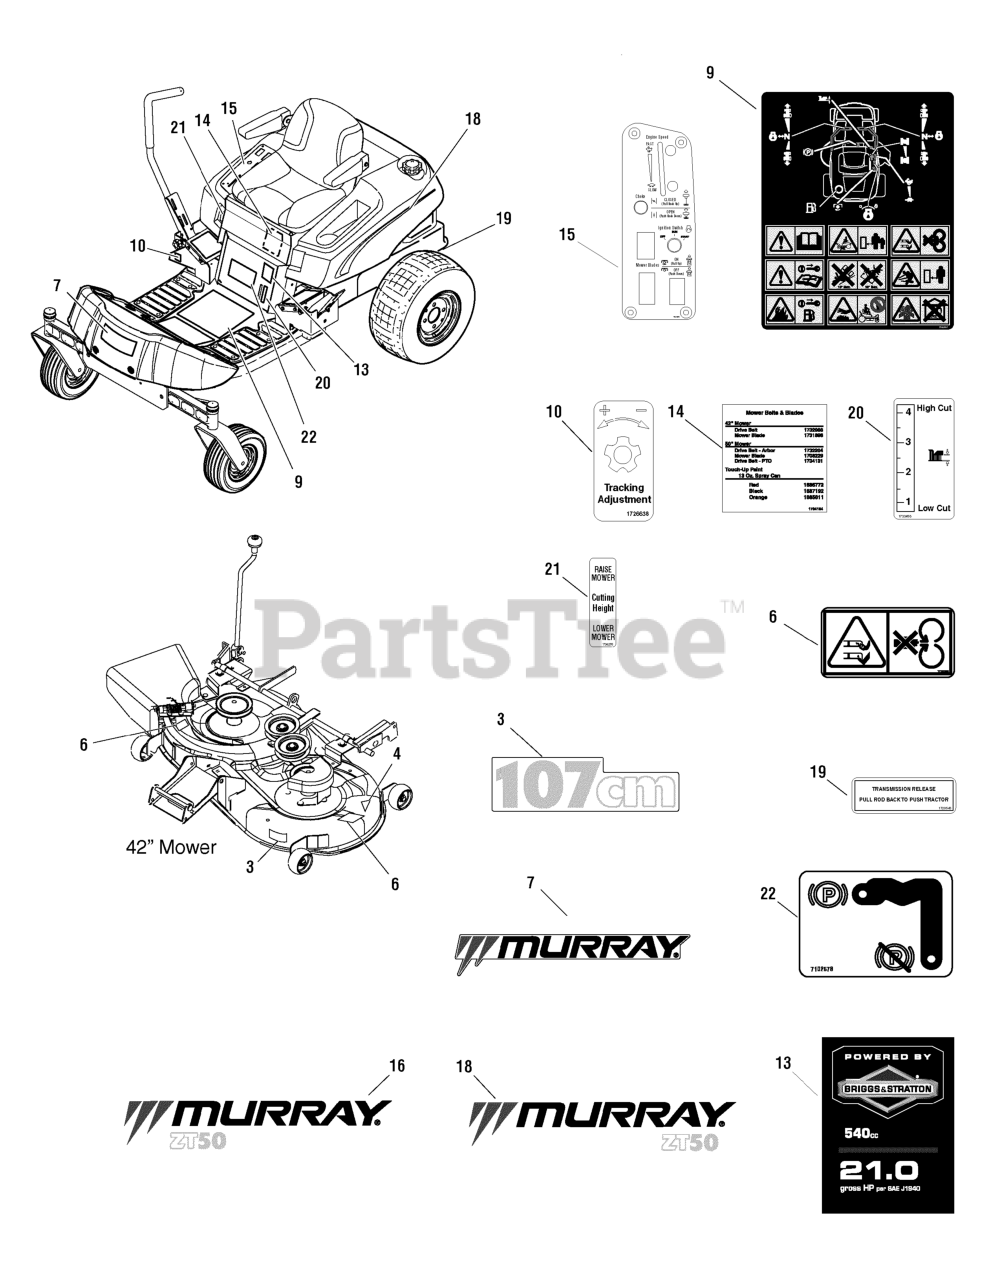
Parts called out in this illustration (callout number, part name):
3	DECAL, Cut Width
4	* DECAL, OPEI Certified ANSI
6	DECAL, Danger Rotating Blades
7	DECAL, Murray
9	DECAL, Operation
10	DECAL, Tracking Adjustment
13	DECAL, Engine/HP
14	DECAL, Belt & Blade
15	DECAL, Instrument Panel
16	DECAL, Murray Strip, Right
18	DECAL, Murray Strip, Left
19	DECAL, Transmission Release Instructions
20	DECAL, Height of Cut without Best Cut
21	DECAL, Switch for Height of Cut
22	DECAL, ZT, Brake, Parking
